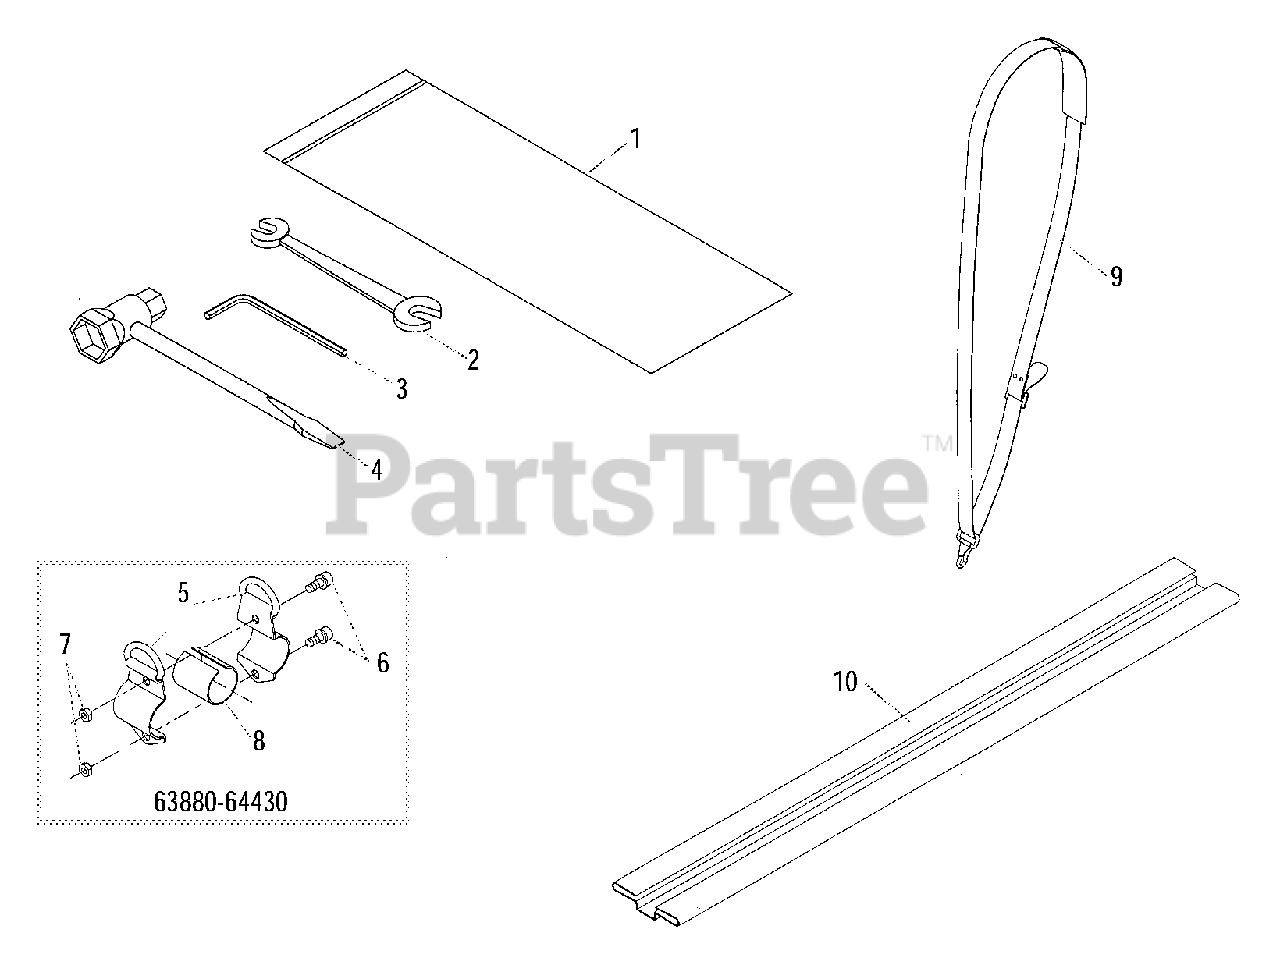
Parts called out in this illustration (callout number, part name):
1	BAG, TOOL
2	SPANNER - 8X10mm
3	HEX KEY - 4mm
4	T-WRENCH
6	SCREW - 5X12
8	SHIM
9	STRAP ASSY
10	COVER, BLADE
63880-64430	MAIN PIPE ASSY
